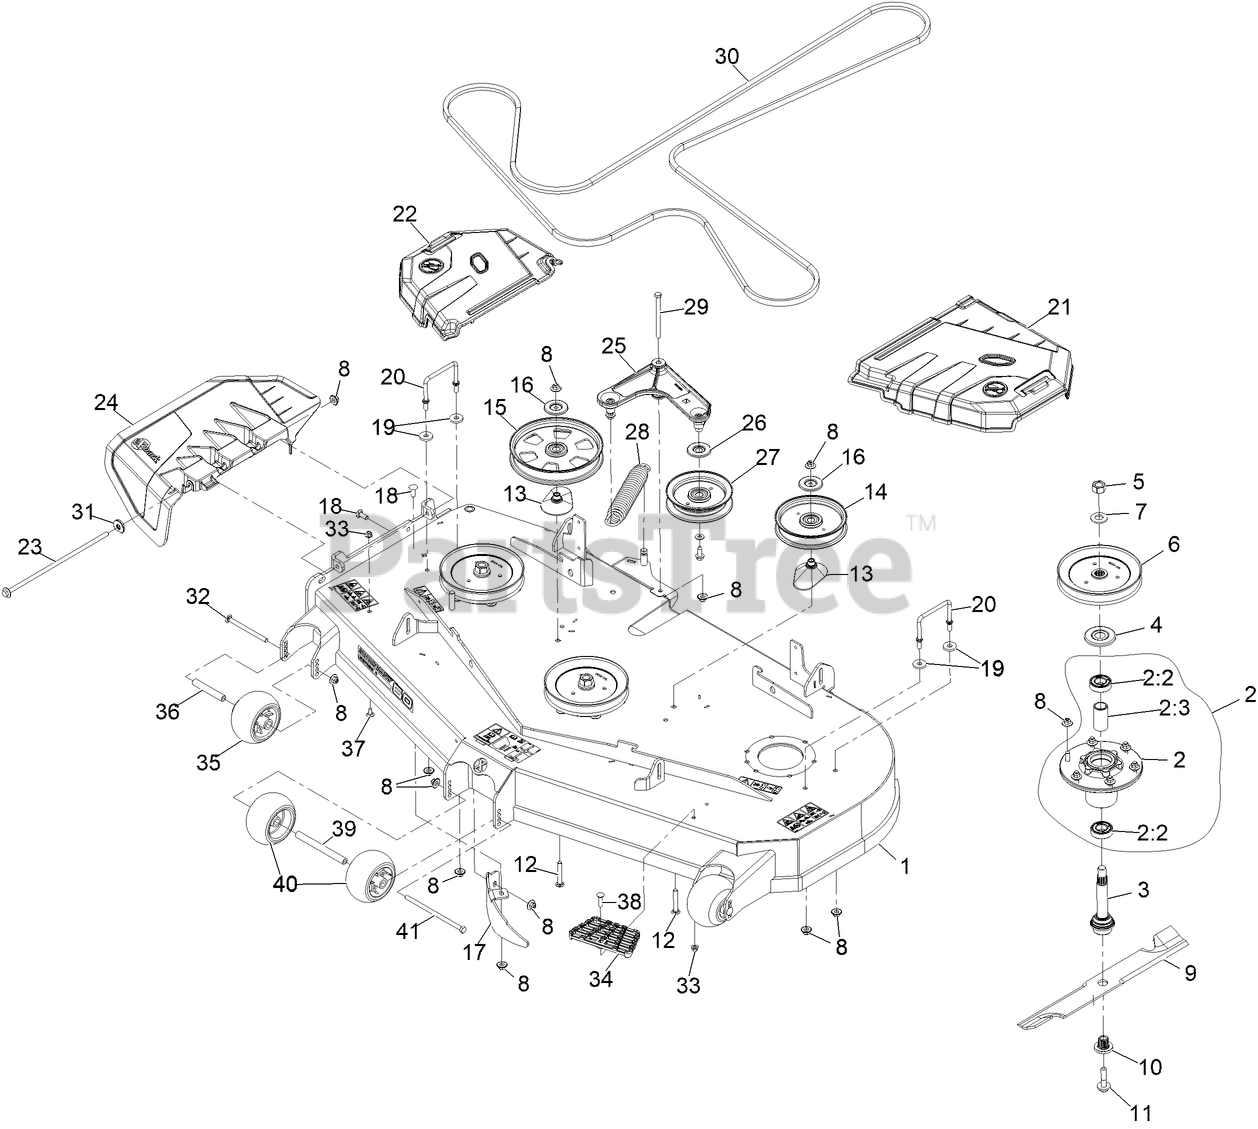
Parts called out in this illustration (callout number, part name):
1	ASM-Deck W/Decals
2	ASM-CUTTER HSG WITH BEARINGS
2:2	BEARING-BALL
2:3	SPACER-BEARING
3	ASM-SPINDLE AND SEAL
4	GUARD-BEARING, TOP
5	NUT-HEX
6	SHEAVE,BLADE DRIVE 7.25
8	Nut-Nyloc 3/8-16 Flg
9	Blade-Extreme 2, 20.50"
10	BUSHING,SPLINED
11	SCREW,SEMS 1/2-20 X 2.19
12	SCREW-CARR
13	SPACER-PULLEY
14	IDLER-PULLEY, FLAT 6.00X1.00
15	PULLEY-IDLER, FLAT
16	SHIELD-DUST
17	DOGLEG - LZ60
18	SCREW-CARR
20	WIREFORM-COVER
21	SHIELD, LT
22	SHIELD, RT
23	Pin, Chute
24	Chute-Deck Discharge
25	ASM-IDLER ARM W/BEARINGS
26	SHIELD-GUARD, DUST
27	IDLER-PULLEY, FLAT
28	SPRING-EXTENSION
29	SCREW-HH
30	Belt, B Section
31	Retainer, Chute
32	BOLT-CARR
33	NUT-HF, NI
34	STEP-DECK
35	ROLLER-SCALP, ANTI
36	SPACER-AXLE
37	SCREW-CARR
38	Bolt-Carriage 5/16-18 X 1 1/4
39	SPACER-WHEEL
40	ROLLER-SCALP, ANTI
41	SCREW-HH
